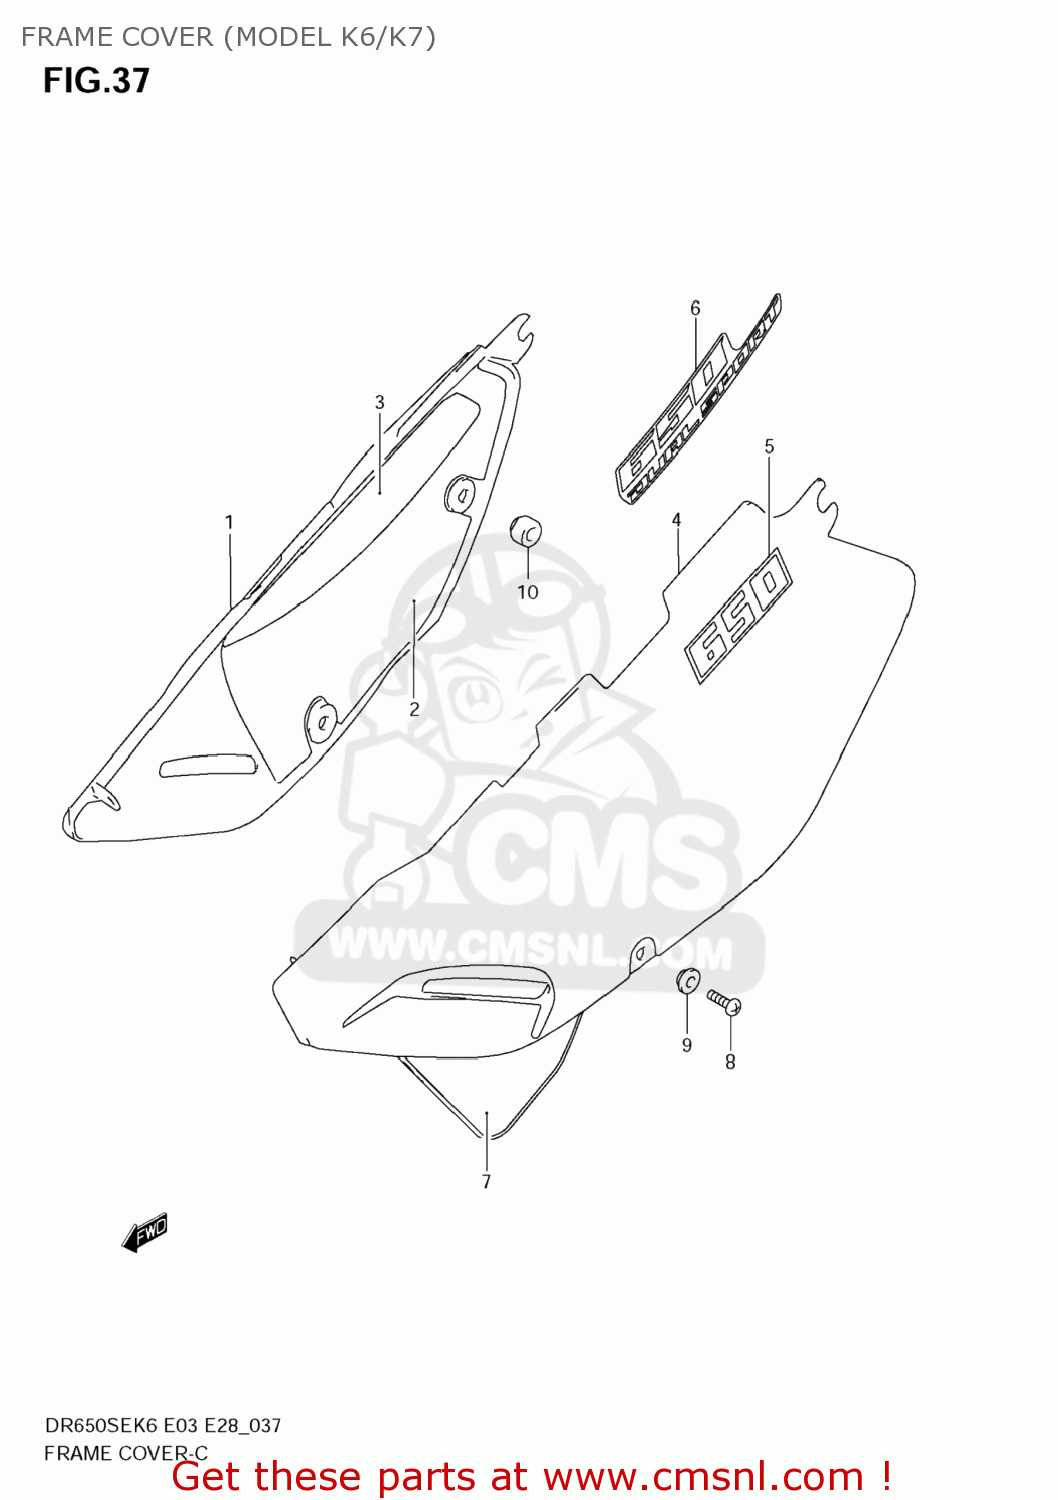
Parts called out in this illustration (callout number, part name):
1	COVER,FRAME,RIGHT
2	SHIELD,FRAME COVER,R NO.1
3	SHIELD,FRAME COVER,R NO.2
4	COVER,FRAME,LEFT
5	EMBLEM,FRAME COVER
6	EMBLEM,FRAME COVER
7	TAPE,LWR
8	SCREW
9	WASHER
10	CUSHION
